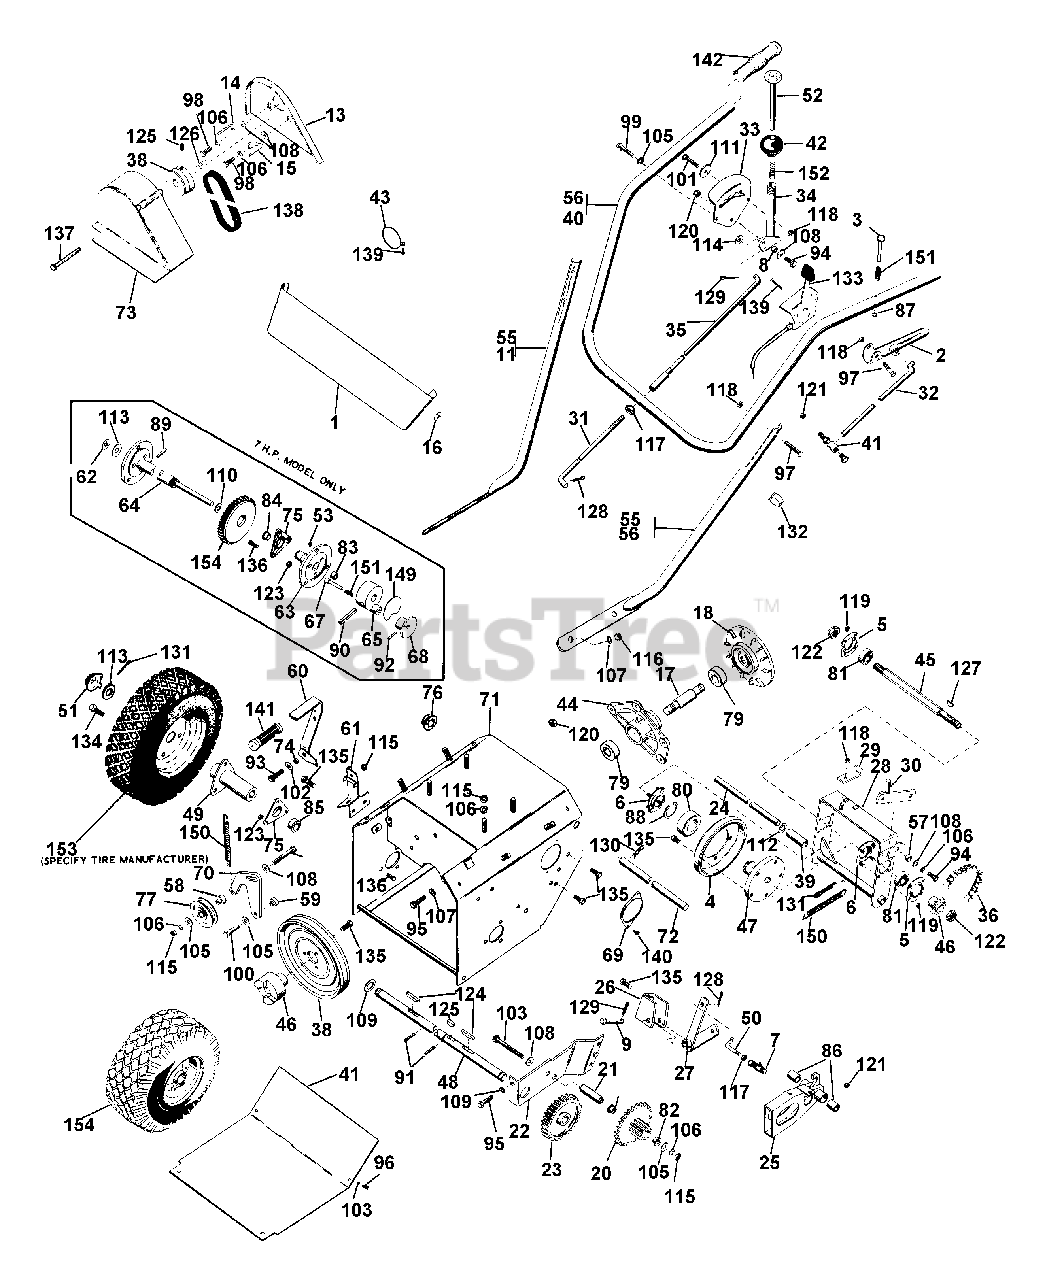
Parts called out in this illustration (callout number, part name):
1	HANDLE BAR PANEL
2	CLUTCH HANDLE
3	CLUTCH LOCK PIN
4	FRICTION DISC
5	BEARING FLANGE
6	BEARING FLANGE
7	BALL JOINT
8	SPACER BUSHING .5 X .32 X .21
9	CLEVIS PIN
10	BOTTOM COV
11	R H LOWER HANDLE BAR
12	L H LOWER HANDLE BAR
13	INNER BELT GUARD
14	R H BELT FINGER
15	L H BELT FINGER
16	HANDLE BAR WASHER
17	SPINDLE
18	DRIVE PLATE
19	JAW COUPLING
20	PINION & SPROCKET
21	PINION STUB SHAFT
22	SUPPORT BRACKET
23	SPUR GEAR, FELLOWS 35T .750 ID
24	BRACKET PIN
25	SLIDING FORK
26	LEVER BRACKET
27	TRANSFER LEVER
28	DISC BRCKT
29	NEUTRAL CATCH
30	THROWOUT LEVER
31	LOWER SHIFT ROD
32	CLTCH ROD
33	SHIFT QUADRANT
34	SHIFT HANDLE
35	SHIFT ROD
36	ROLLER CHAIN
37	ENGINE SHEAVE
40	UPPER HANDLE BAR
41	BALL JOINT
42	SHIFT BALL
44	BEARING HOUSING
45	HEX SHAFT
46	9 TOOTH SPROCKET
47	FRICTION DISC HUB
48	AXLE SHAFT
49	WHEEL HUB
50	CONNECTING LINK
51	HUB CAP
52	SHIFT RELEASE HANDLE
53	HYDRAULIC DRIVE FITTING
54	R H LOWER HANDLE BAR
55	L H LOWER HANDLE BAR
56	UPPER HNDLBAR PLATED
57	SPACER BUSHING .5 X .32 X .163
58	BEARING SPACER
59	SHOULDER SPACER
60	CLTCH LEVER
61	CLTCH BRCKT
62	PUSHNUT
63	L H AXLE
64	R H AXLE SHAFT
65	LOCKOUT HUB
66	CARBURETOR COVER
67	PIN
68	KNOB
70	IDLER ARM
71	TRACTOR FRAME
72	FORK SHAFT
73	OUTER COVER
74	SPACER .50 X .32 X .42
75	SUPPORT, BEARING
76	CAP, .50 ROD YWZC
77	IDLER
78	DIFFERENTIAL ASSEMBLY
79	BRG-BALL .750X1.750X.50
80	BRG-N-THRST 1.26X2.18X.63
81	BRG-BALL .500X1.38X.437
82	BSHG-FLG .625X.750X.500X.875BR
83	BSHG-SLV .562X.625X.625 BRZ
84	BSHG-FLG.875X1X.625X1.250 BR
85	BSHG-FLG .750X1.000X.625X1.250
86	BSHG-SLV .500X.625X.500 BR
87	RG-RTNG-EXT .250X.031
88	RG-RTNG-EXT 1.250X.050
89	PIN-ROLL .188X1.25
90	PIN-ROLL .250X1.25
91	PIN-ROLL .188X1.00
92	PIN-ROLL .093X1.00
93	BLT-HEX .31-18X1.00 PL GR 2
94	BLT-HEX .31-18X.75 PL GR2
95	BLT-HEX .38-16X.75 PL GR2
96	BLT-HEX .25-20X.50 PL GR2
97	BLT-HEX .25-20X1.50 PL GR5
98	BLT-HEX .31-24X.75 PL GR5
99	BLT-HEX .25-20X1.25 PL GR5
100	BLT-HEX .31-18X1.25 PL GR2
101	BLT-HEX .25-20X1.25
102	BLT-HEX .31-18X1.75 PL GR2
103	BLT-HEX .31-18X2.75 PL GR2
104	SCR-SET .32-18X.38 SKHCUPNL OH
105	WSHR-LK .250X.077 HVY PL
106	WSHR-LK .312X.097 PL HVY
107	WSHR-LK .375X.115 HVY PL
108	WSHR-FL-STL .38X.875X.083 PL
109	WSHR-FL-STL .755X1.375X.125
110	WSHR-FL-STL .880X1.380X.062
111	WSHR-FL-STL .281X1.250X.048PL
112	WSHR-FL-STL .505X.875X.024 PL
113	WSHR-FL-STL .755X2.000X.125
114	WSHR-FL-STL.406X.812X.065PL
115	NUT-HEX .312-18
116	NUT-HEX .375-16
117	NUT-HEX .312-24 PL
118	NUT-LK-CTR .250-20 PL
119	NUT-LK TOP 10-24 PL
120	NUT-LK .312-18 GR A PL
121	NUT-LK-CTR .312-24 PL
122	NUT-LK-CTR .50-20 PL
123	NUT-LK-FLG .250-20 PL
124	KEY-FTHR .188X1.25X.187 SAE
125	KEY-WDRF .25X.750X.313 SAE91
126	KEY-SQ .188X1.0X.188 SAE 8630
127	KEY-WDRF .125X.625X.250 SAE5
128	PIN-COTR .09X.75 PL
129	PIN-COTR .12X1.0 PL
130	PIN-HAIR INT .08X.38X1.42 YWZC
131	PIN-COTR .12 X 1.25 PL
133	THROTTLE CONTROL
134	BLT-WHL .50-20X.50 GR5 PL
135	BLT-SERHFWH .31-18X.50 PL
136	SCR-SLTR-SERNK .25-20X.62 PL
137	BLT-HFWH .31-24X3.62 PL
138	V-BELT, SAE 380-RAW EDGE
139	SCR-TAP 10-12X.50 CRPH PL A
140	SCR-TAP 10-24X.25 CRSLPH PL 1A
142	GRIP
143	SNO-THRO HELICON PATENT LABEL
144	CLUTCH LABEL
145	CARB. COVER LABEL
146	SNO THRO SHIFT LABEL
147	5 H P ENGINE DECAL
148	7 HP ENGINE DECAL
149	DIFFERENTIAL LOCK LABEL
150	SG-TENS .125X.437X5.5 WLD 20
151	SG-COMP .028X.34X1.062 WLD75
152	SG-COMP ??X.44X?? WLD 10
153	TIRE & WHEEL ASSEMBLY GOODYEAR
153	TIRE 4.10/3.50X6
153	TIRE 4.10/3.50X6 2PLY
153	TUBE
153	WHL 6 IN O.D.
154	TIRE & WHEEL ASSEMBLY CARLISLE
154	TIRE 12.5/4.50-6
164	TUBE
164	WHL 6 IN O.D.
